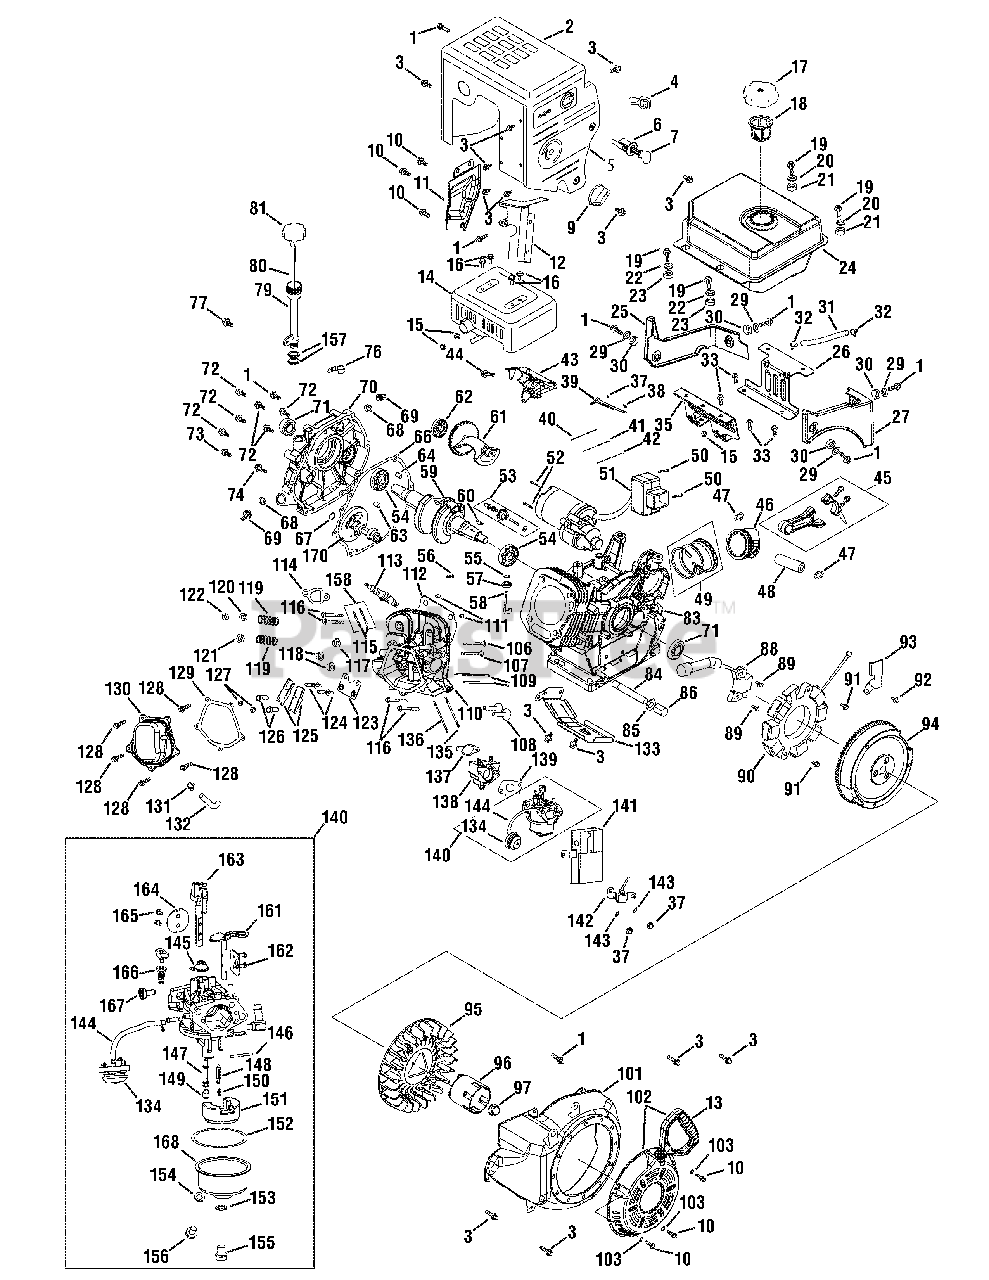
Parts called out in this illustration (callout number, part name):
1	Bolt, M6 X 16
2	Muffler Shield
3	Bolt, M6×12, Zinc Coating
4	Throttle Control Knob
5	Control Panel
6	Ignition Switch Assembly
7	Key
9	Choke Knob
10	Bolt, Flange, M6×10
11	Muffler Baffle
12	Carburetor Heat Shield
13	Starter Handle
14	Muffler Assembly
15	Nut, M8 - 1.25
17	Fuel Cap
18	Fuel Filter
19	Flange Bolt, M8 X 20
20	Flat Washer
21	Bushing
22	Flat Washer
23	Bushing
24	Fuel Tank
25	Fuel Tank Shroud
26	Fuel Tank Mounting Bracket
27	Engine Shroud
29	Flat Washer
30	Bushing
31	Fuel Line
32	Fuel Line Clamp
33	Bolt, Flange, M8×14
35	Fuel Tank Mounting Bracket
37	Nut, Flange, M6
38	Bolt, M6×21, Governor Arm
39	Governor Arm Bracket
40	Governor Spring
41	Throttle Return Spring
42	Governor Rod
43	Throttle Control Assembly
44	Bolt, Flange, M6 × 14
45	Connecting Rod Ass’y Complete
46	Piston
47	Piston Pin Clip
48	Piston Pin
49	Piston Ring Set - Complete
50	Screw, M4 X 55
51	Electric Starter
52	Flange Bolt, M8 X 55
53	Governor Assembly
54	Bearing
55	Governor Shaft Washer
56	Governor Shaft Clip
57	Oil Seal - Governor Shaft
58	Governor Arm Shaft
59	Crankshaft Assembly
60	Flywheel Key
61	Balance Shaft
62	Bearing
63	Dowel Pin
64	Dowel Pin, 7 X 14
64	Dowel Pin, 7 x 14
66	Crankcase Cover Gasket
67	Washer
68	O-Ring
69	Oil Fill Plug
70	Crankcase Cover
71	Oil Seal - PTO Side
72	Flange Bolt, M8 X 38
73	Bolt, M8 X 45
74	Bolt, M8 X 35
76	Oil Tube Support Bracket
77	Flange Bolt M6 X 16
79	Dipstick Tube
80	Dipstick
81	Oil Cap
83	Crankcase
84	Oil Drain Pipe
85	Oil Drain Washer
86	Oil Drain Plug
88	Ignition Coil
89	Bolt, Flange, M6×28
90	Stator
91	Flange Bolt, M6 X 30
92	Flange Bolt, M6 X 8
93	Alternator Wire Clamp Bracket
94	Flywheel
95	Cooling Fan
96	Starter Cup
97	Nut, M16 - 1.5
101	Blower Housing
102	Recoil Starter Assembly
103	Flat Washer Recoil
106	Exhaust Valve
107	Intake Valve
108	Valve Lifter (Tappet)
109	Push Rod
110	Cylinder Head
111	Dowel Pin, 12 X 20
111	Dowel Pin, 12 x 20
112	Cylinder Head Gasket
113	Spark Plug
114	Muffler Gasket
115	Muffler Stud
115	Exhaust Stud
116	Flange Bolt, M10-1.25 X 87
117	Intake Valve Seal
118	Valve Spring Retainer
119	Valve Spring
120	Valve Spring Retainers -Exhaust
121	Valve Spring Retainer-Intake
122	Exhaust Valve Cap
123	Push Rod Guide
124	Rocker Stud Bolt
125	Rocker Arm
126	Pivot Adjusting Nut
127	Pivot Locking Nut
128	Bolt -Valve Cover, M6 X 16
129	Valve Cover Gasket
130	Valve Cover
131	Breather Hose Clip
132	Breather Hose
133	Cylinder Baffle
134	Primer
135	Carburetor Stud, M6 X 8 X 98
136	Carburetor Stud, M6 X 8 X 118
137	Intake Gasket
138	Carburetor Insulator
139	Carburetor Gasket
140	Carburetor Assembly
141	Heater Box
142	Choke Assembly
143	Lock Washer
144	Primer Hose
145	Throttle Pressure Plate
146	Float Pin
147	Main Nozzle
148	Needle Valve
149	Main Jet
150	Needle Valve Spring
151	Float
152	Bowl Gasket
153	Fuel Bowl Gasket
154	Fuel Drain Plug Gasket
155	Fuel Bowl Mounting Bolt
156	Fuel Drain Plug
157	O-Ring
158	Muffler Stud Assembly
161	Choke Shaft
162	Choke Plate
163	Throttle Shaft
164	Throttle Plate
165	Screw
166	Idle Jet Assembly
167	Idle Speed Adjusting Screw
168	Fuel Bowl
170	Camshaft Assembly
